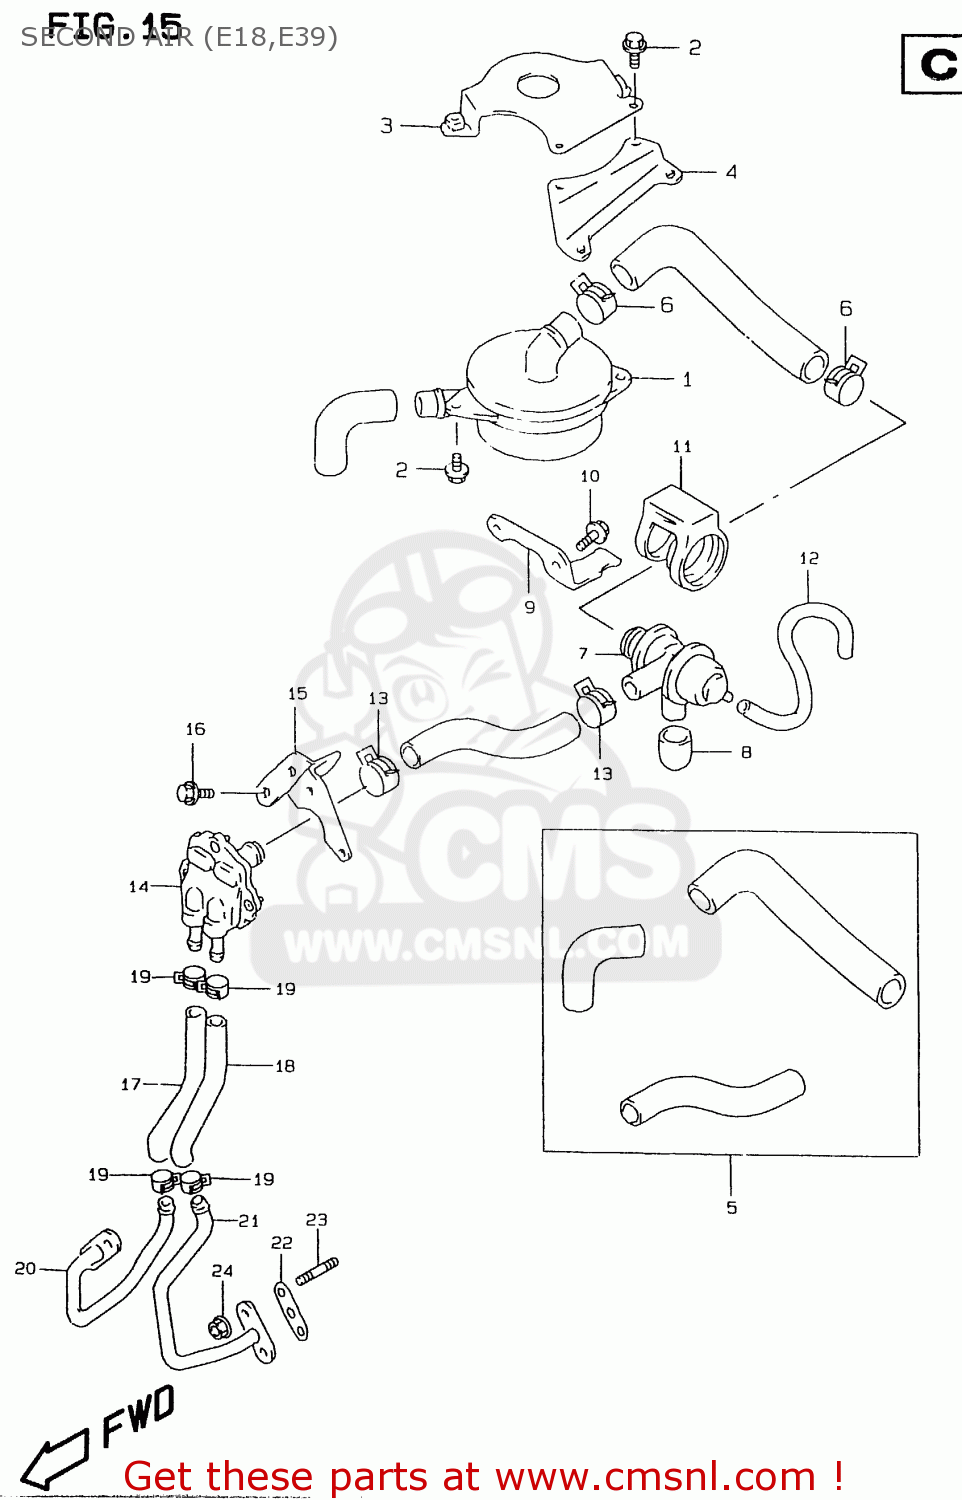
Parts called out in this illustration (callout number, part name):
1	CLEANER ASSEMBLY,SECOND AIR
2	BOLT
3	BRACKET,2ND AIR CLEANER
4	BRACKET,2ND AIR CLNR SUPPORT
5	HOSE SET, 2ND AIR
6	CLIP
7	VALVE ASSY,2ND AIR SWITCHING
8	CAP,SWITCHING VALVE
9	BRACKET, SWITCHING VALVE
10	BOLT
11	CUSHION,2ND AIR VALVE
12	HOSE(4.5X8.5X600)
13	CLIP
14	VALVE ASSY,2ND AIR REED
15	BRACKET, REED VALVE
16	BOLT
17	HOSE,2ND AIR REED VALVE,R
18	HOSE,2ND AIR REED VALVE,R
19	CLIP
20	PIPE,2ND AIR,R
21	PIPE,2ND AIR,L
22	GASKET,SECOND AIR PIPE (N (NAS)
23	STUD BOLT
24	NUT
